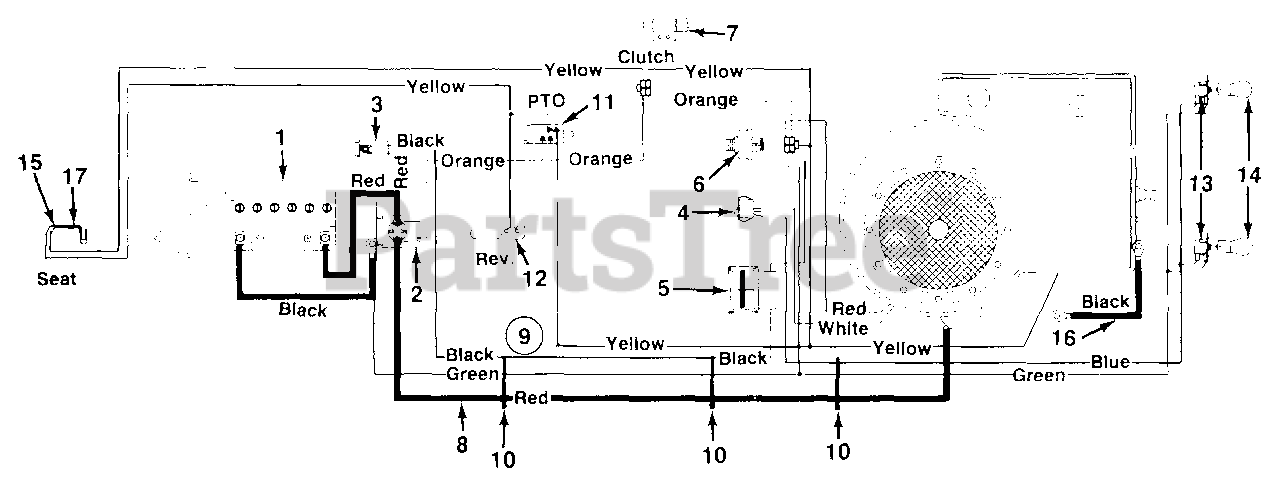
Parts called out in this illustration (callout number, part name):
1	Battery
2	Solenoid
3	Fuse 7.5 Amps
4	Light Switch
5	Ammeter
6	Ignition Switch
7	Safety Switch (Clutch)
8	Electric Wire 30" Lg. (B&S)
9	Wire Harness w/o Ammeter (B&S)
10	Cable Tie
11	Safety Switch (Deck)
12	Safety Switch (Reverse)
13	Socket
14	Bulb (Headlight)
15	Safety Switch (Seat)
16	Ground Wire 7.5" Lg.
17	Safety Switch (Seat)
